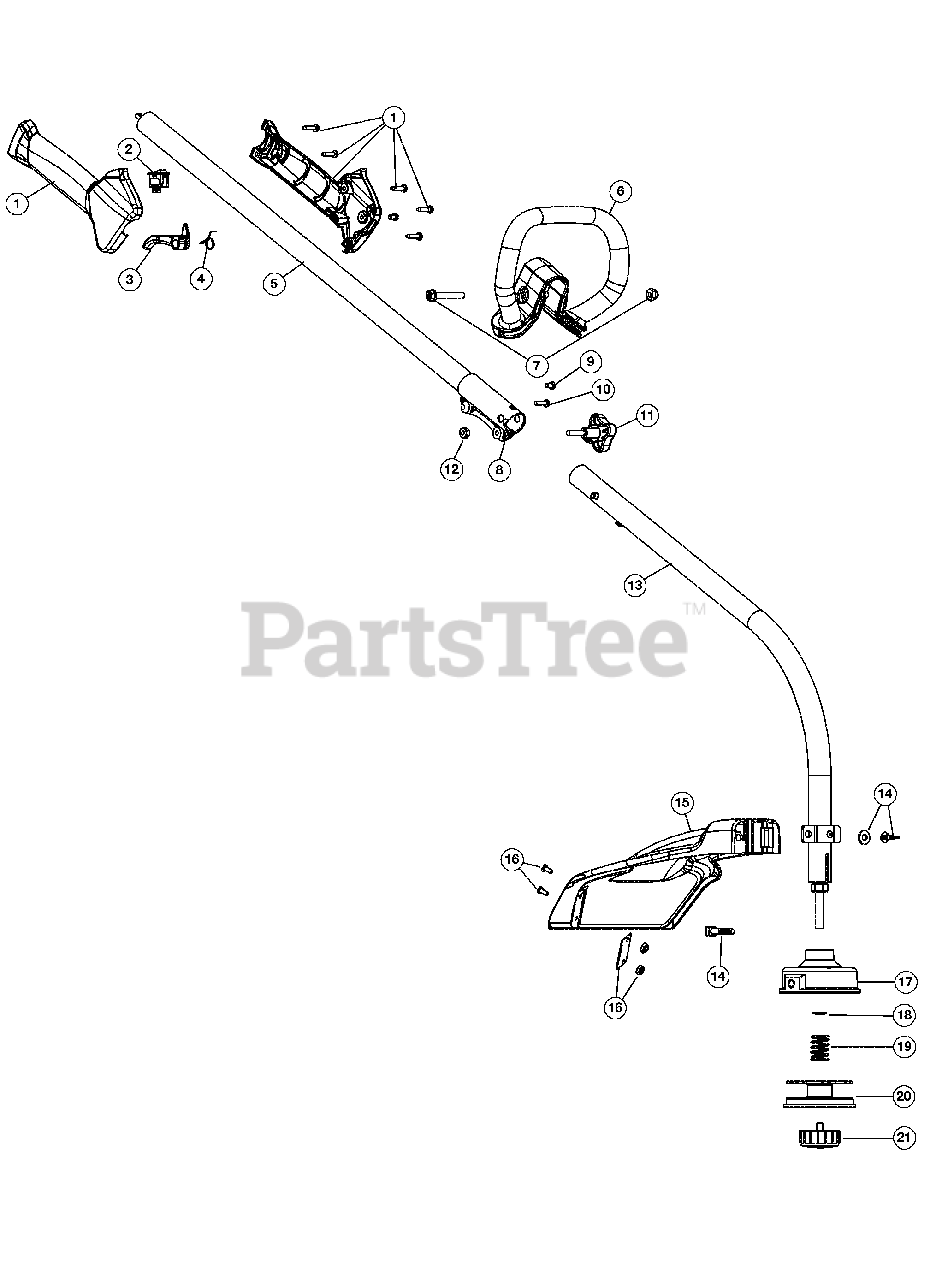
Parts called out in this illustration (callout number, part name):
1	Throttle Housing Assembly (Incl. 2-4)
3	Throttle Trigger
4	Throttle Trigger Spring
5	Upper Shaft Housing Assembly
6	D-Handle (Incl. 7)
7	D-Handle Bolt
8	Split Boom Coupler (Incl. 9-12)
9	Anti-Rotation Screw
11	Adjustment Knob
12	Knob Retainer Nut
13	Lower Shaft Housing Assembly
14	Shield Mounting Hardware
15	Shield Assembly (Incl. 16)
16	Blade Assembly
17	Outer Spool Assembly (Incl. 18)
20	Inner Reel
21	Bump Head Knob Assembly
